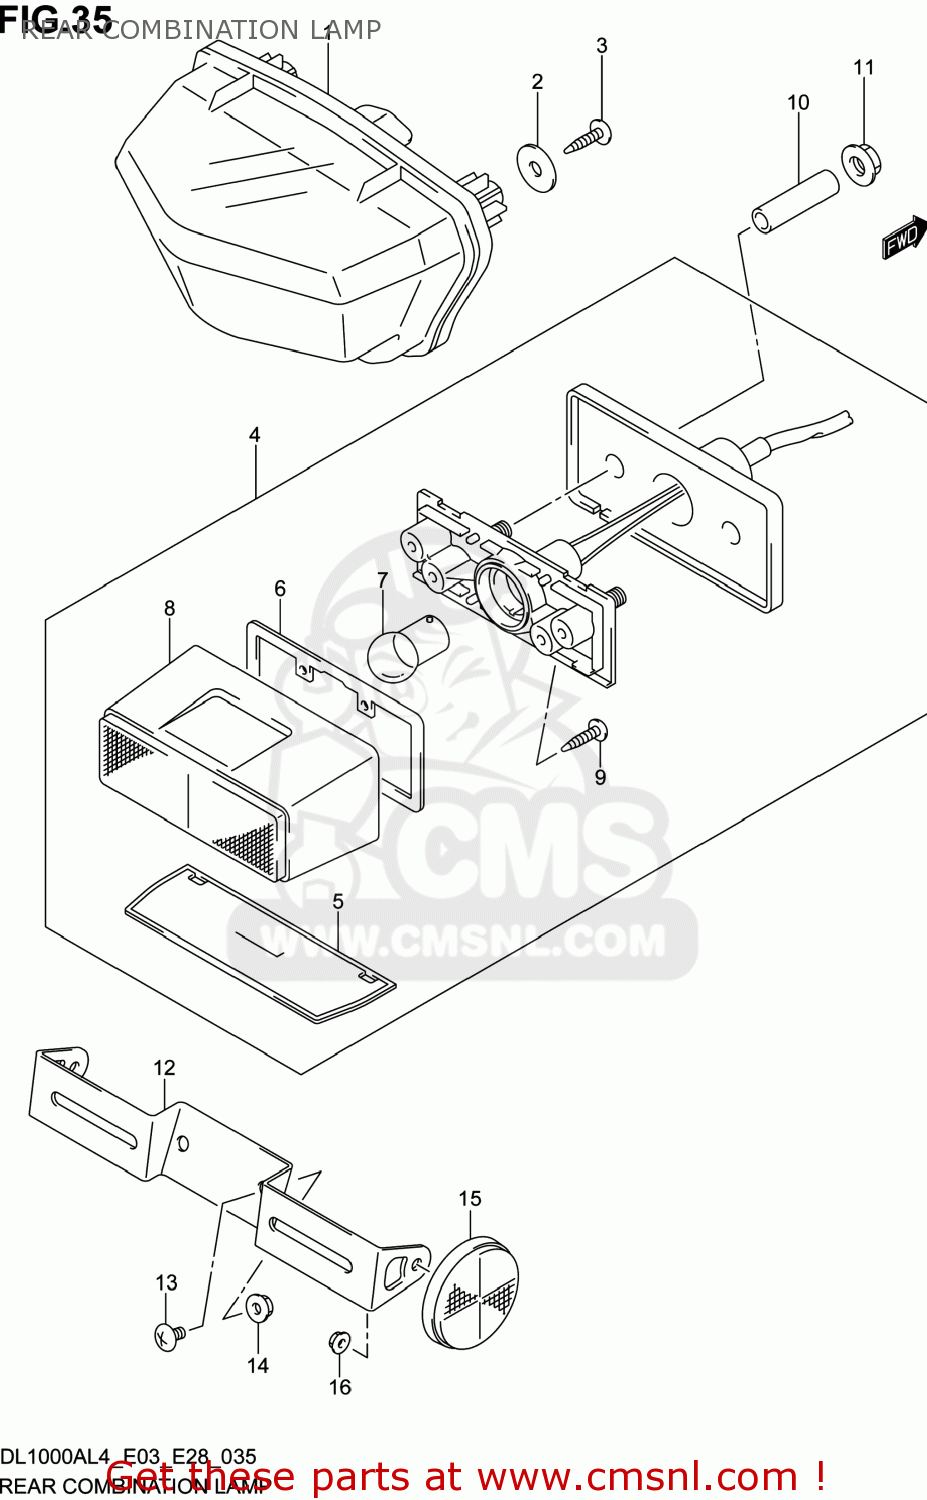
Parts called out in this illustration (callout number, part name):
1	LAMP ASSY,REAR COMB
2	WASHER(5.5X20X1.2)
3	SCREW
4	LAMP ASSY,LICENSE
5	LENS,LICENSE LAMP
6	GASKET (NAS)
7	BULB(12V5W,BF150-40160A)
8	COVER,LICENSE LAMP
9	SCREW
10	SPACER(6.5X9X33.3)
11	NUT
12	BRACKET,LICENSE PLATE
13	SCREW
14	NUT
15	REFLECTOR ASSY,RR SIDE
16	NUT
